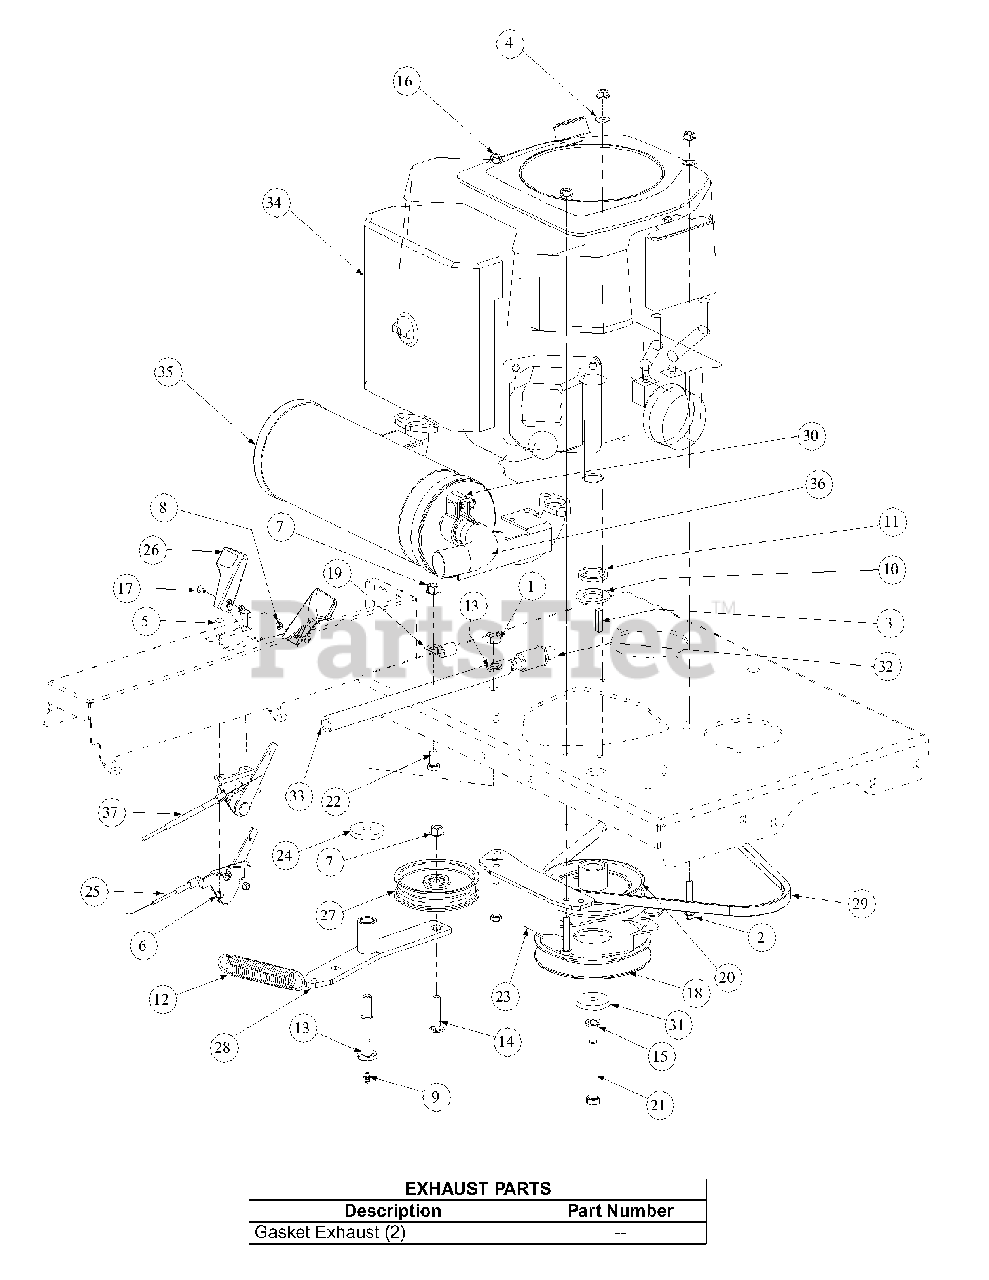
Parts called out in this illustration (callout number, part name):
1	Hex Nut, 7/16-14
2	HHCS, 5/16-18, 1-3/4
3	Key, 1/4 x 1-1/8
4	Flat Washer, 5/16
5	Round Hd. Machine Screw, 10-32 x 3/4
6	Lock Nut, Nylon Insert, 10-32
7	Flange Lock, Hex Nut, 3/8-16
8	Nut Washer, W/Star, 8-32
9	Grease Fitting, 1/4-28 x 3/16
10	Flat Washer
11	Engine Spacer
12	Extension Spring, 1.0 OD x 5.00
13	Shoulder Screw, 7/16-14
14	Hex Carriage Screw, 3/8-16, 1.75
15	Lock Washer, 7/16
16	Hexflange Lock Nut, 5/16-18
17	Machine Screw, 8-32, .375
18	Electric Clutch
19	Clip, Heat Shield Cable
20	Transmission Drive Pulley
21	Capscrew, 7/16-20 x 3.00
22	Hex Cap Screw, 3/8-16, .750
23	Retainer Clutch Assembly, Ogura
24	Flat Washer, 7/16 ID x 1.75 OD x .25
25	Throttle, Control Cable,45.0
26	Control Throttle Knob
27	Flat Pulley with Flanges
28	Engine Idler Arm Assembly
29	V Belt, A Section x 47.3
29	Belt: To be used with new sub-frame
30	Tube Clamp, 1.375
31	Flat Washer, 7/16 IDx 1.750 OD x .250T
33	Oil Drain Hose
34	18HP Kohler Engine
35	18HP Kohler Exhaust
36	Muffler Accessory Exhaust Tube
37	Choke, Control Cable, 38.0
